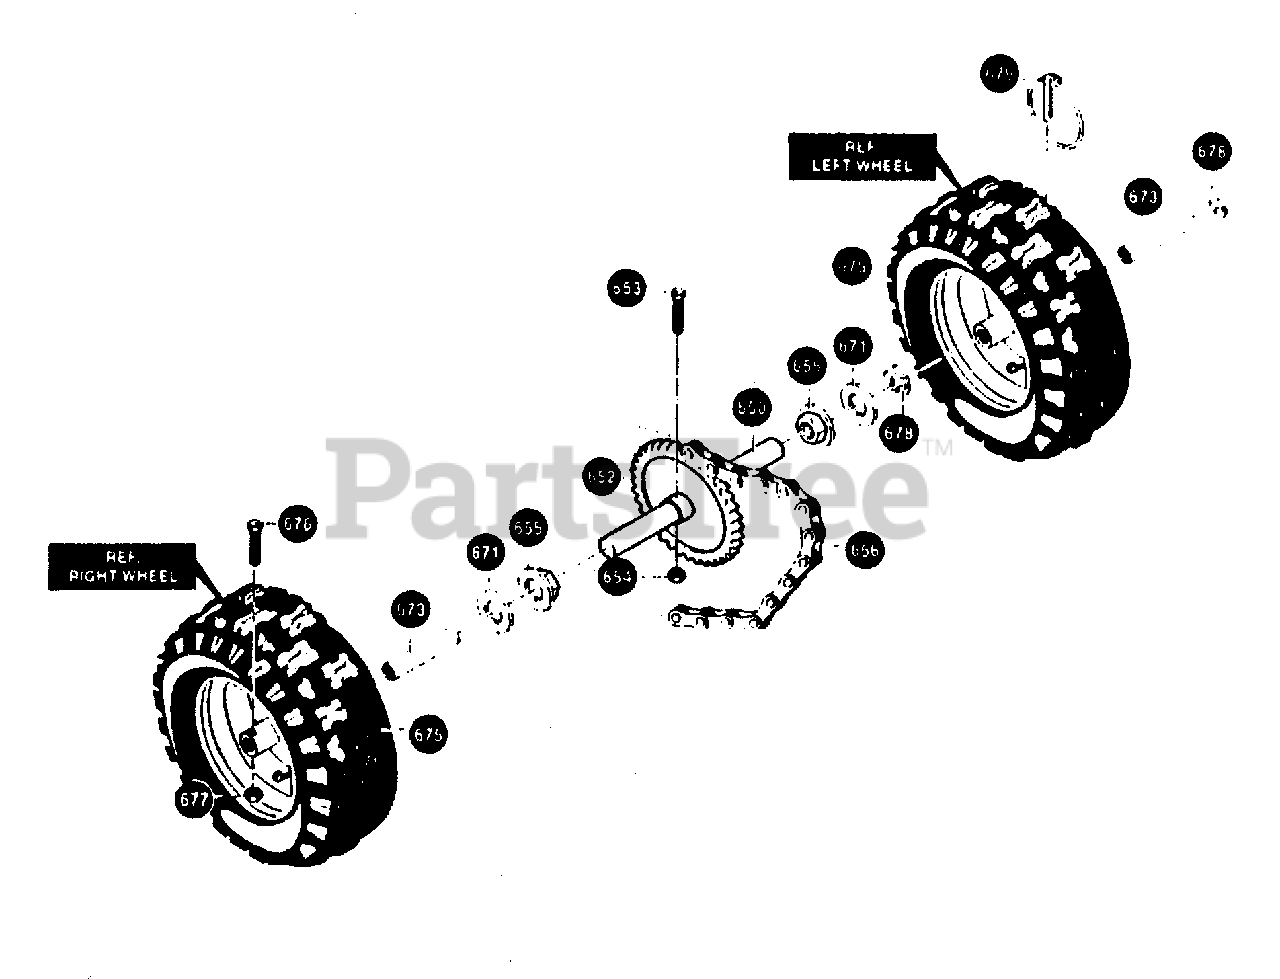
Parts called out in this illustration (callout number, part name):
650	SHAFT, AXLE
652	SPRKT & HUB, ASSY
653	SCREW, 1/4-20X2.25
654	NUT, 1/4-20
655	BEARING, FLANGE
656	CHAIN, ROLLER
671	FLATWASHER
673	BUSHING, WHEEL 4" LG
675	TIRE & RIM
676	SCREW, SHR 1/4-20X1.7
677	NUT, 1/4-20
679	PIN, KLIK .25 X 1.38 DIA
